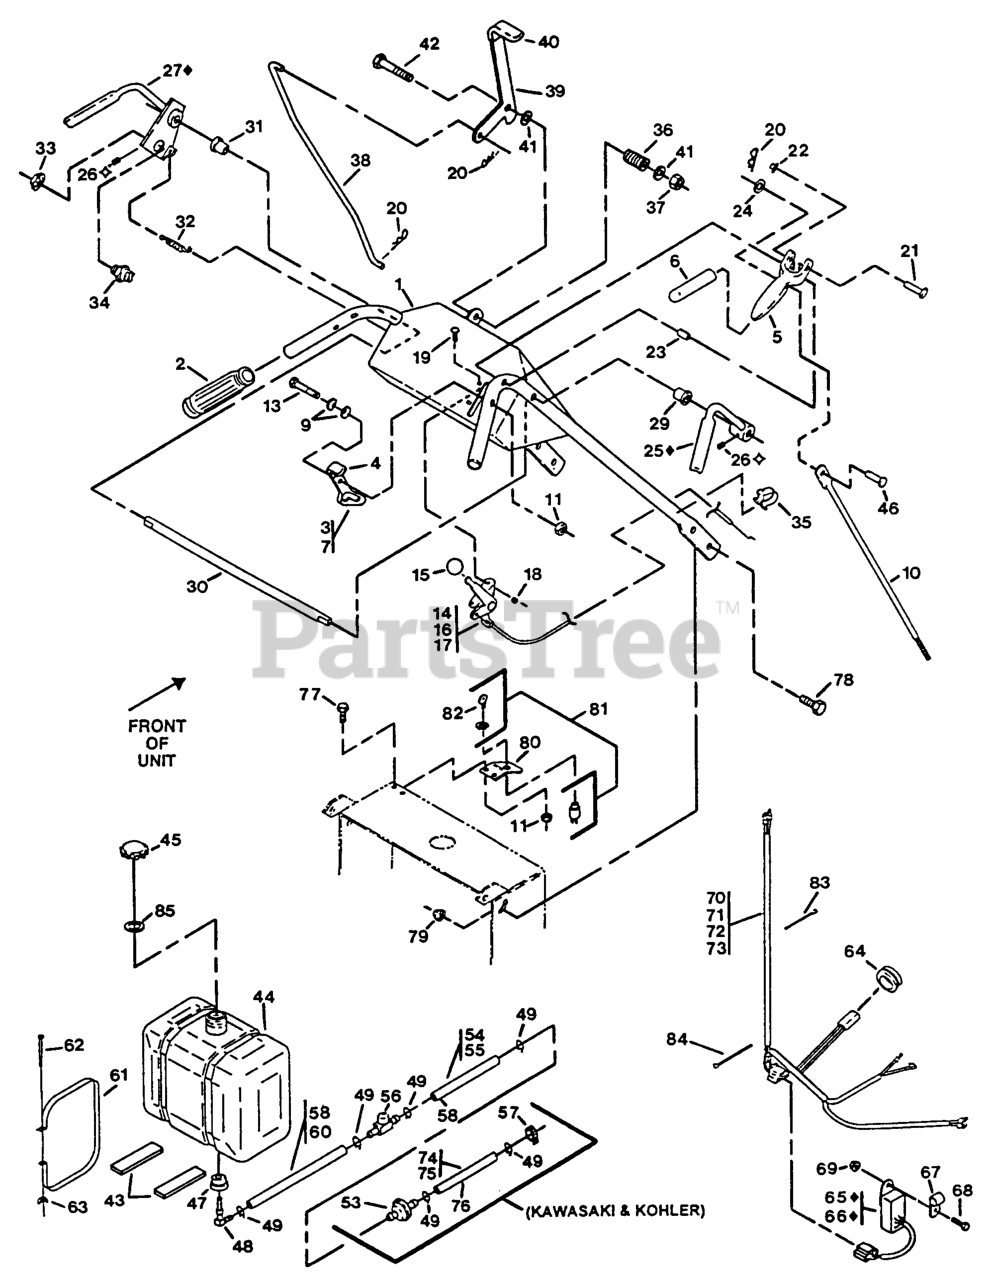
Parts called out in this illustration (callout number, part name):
3	LATCH,W/GRIP LH
4	GRIP-LATCH
5	DRIVE LEVER ASM
6	GRIP-LEVER, DRIVE
7	LATCH,W/GRIP RH
9	WASHER-SPRING
10	LINKAGE-WHEEL, DRIVE
14	CABLE-CONTROL, THROTTLE
15	KNOB-BALL
19	BOLT-CARR
20	PIN-COTTER
21	PIN-LEVER, DRIVE
22	NUT-PUSH
23	PIN-ROLL
26	SCREW-SET
29	BUSHING-NYLON
30	ROD,CONNECTING
31	BUSHING,FLANGED
32	SPRING-EXTENSION
34	SWITCH,OPERATOR CNTRL
35	CLIP-CABLE
36	SPRING-COMPRESSION
38	LINKAGE-BLADE, UPPER
40	GRIP-LEVER
43	PAD,PLASTIC TANK
45	CAP-FUEL
46	PIN,CLEVIS
48	ELBOW-TANK, FUEL
49	CLAMP
54	HOSE-LINE, FUEL
55	LINE-FUEL
56	VALVE-FUEL
57	CLAMP-HOSE
58	HOSE-FUEL
59	HOSE-FUEL
62	SCRW,MACH CRPH
63	WINGNUT
64	GROMMET
67	CLIP-LOOM
70	HARNESS,WIRING KAW METRO
74	HOSE-LINE, FUEL
75	HOSE-FUEL
76	LINE-FUEL
81	SWITCH & KEY (INCLUDES NU
82	KEYS-IGNITION (SPARE PAIR
83	TIE-PLASTIC
84	TIE-CABLE
